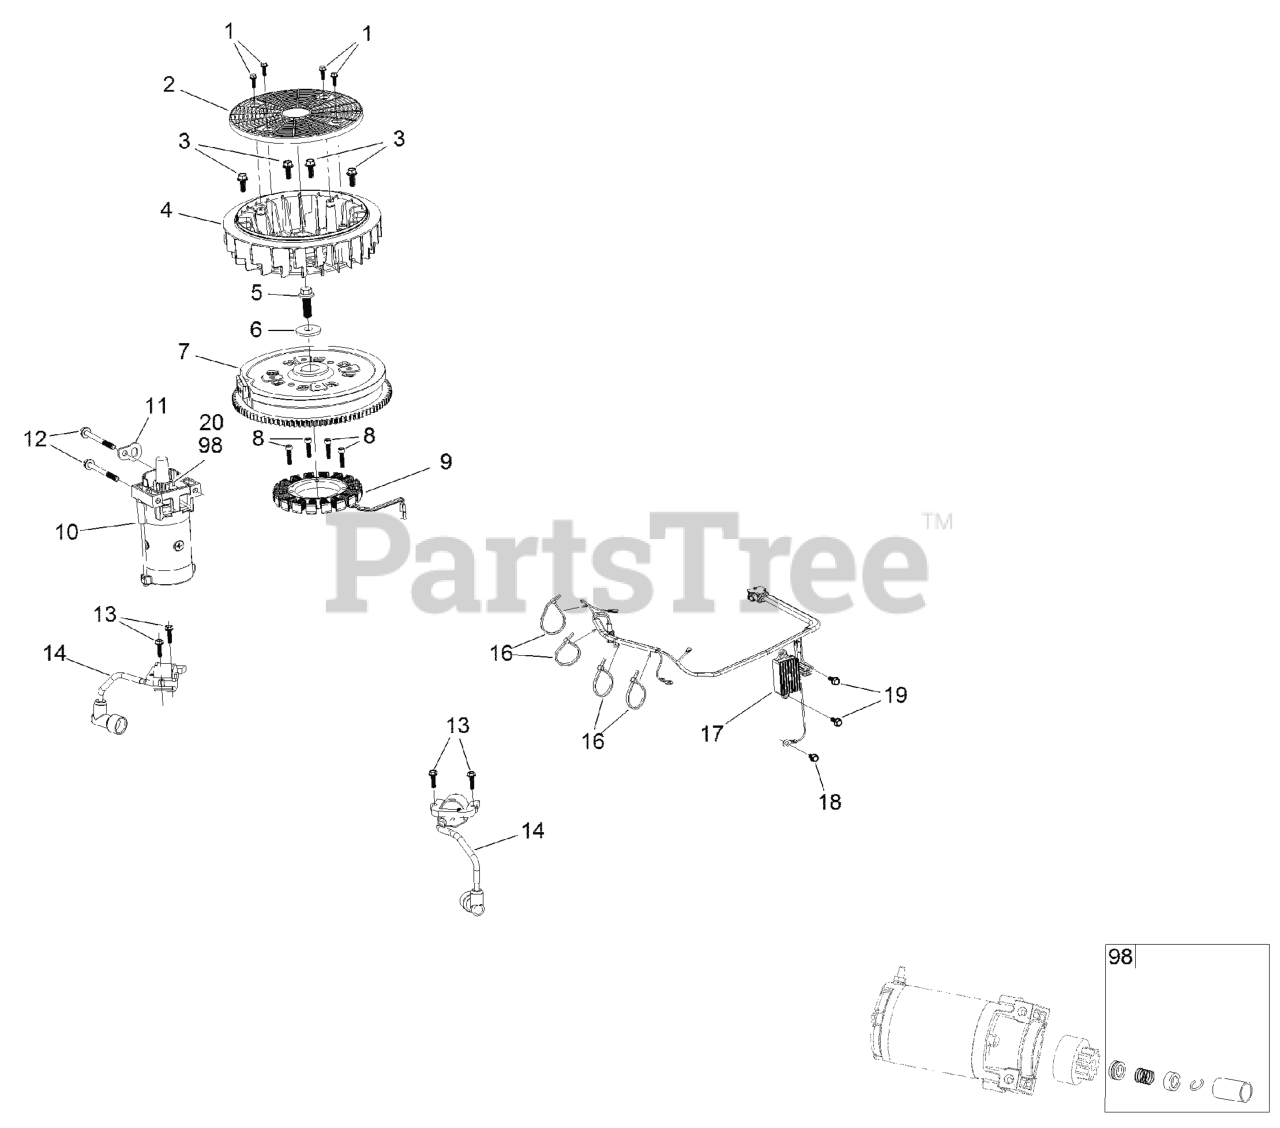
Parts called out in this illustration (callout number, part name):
1	SCREW-HWH
2	SCREEN-ROTATING
3	SCREW-HWH
4	FAN-COOLING
5	SCREW-HWH
6	WASHER-FLAT
7	FLYWHEEL
8	SCREW-HSH
9	ALTERNATOR
10	MOTOR-STARTER
11	BRACKET-LIFT
12	SCREW-HHF
13	BOLT-FLANGE
14	IGNITION COIL ASM
16	TIE-ZIP
17	REGULATOR-VOLTAGE, W/HARNESS
18	SCREW-HHF
19	SCREW-HHF
20	PINION-STARTER
98	STARTER REPAIR KIT
